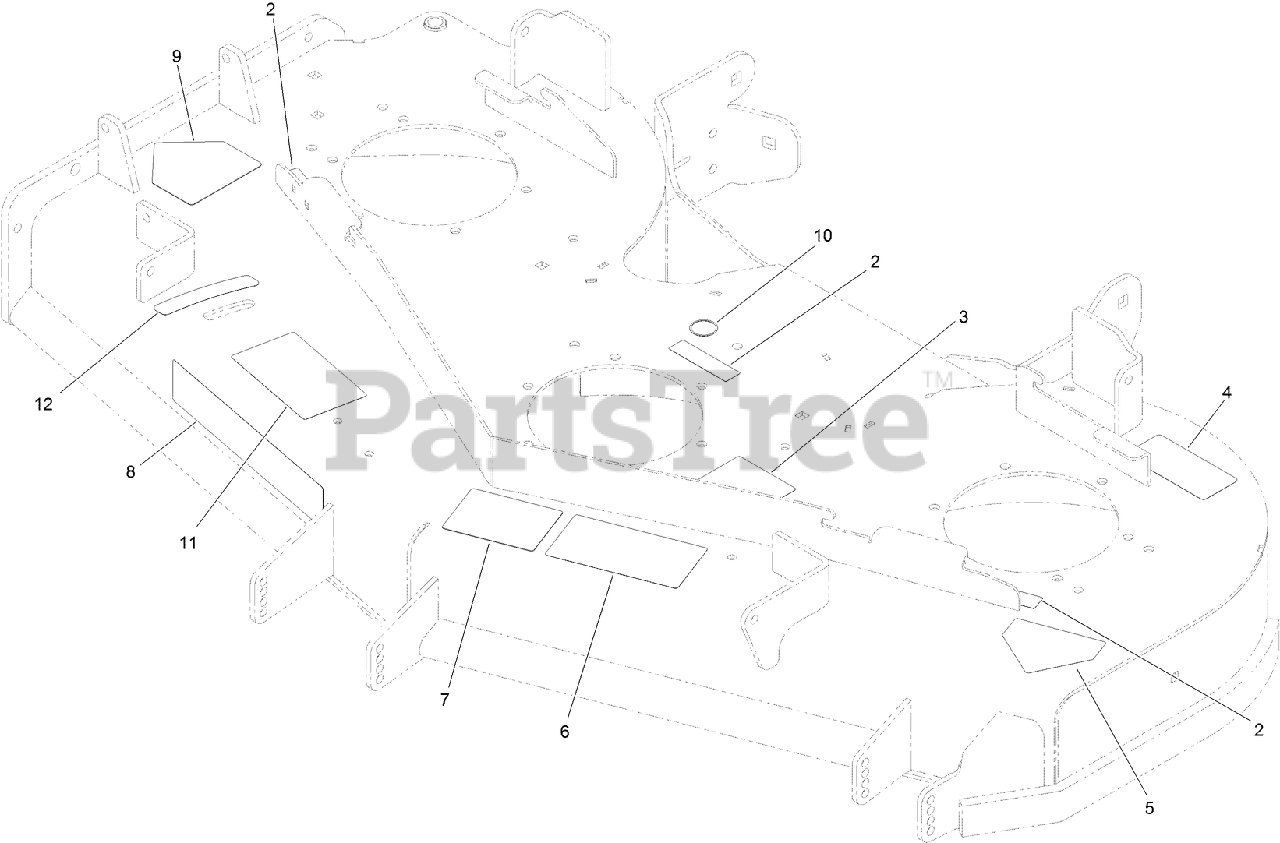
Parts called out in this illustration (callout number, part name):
2	DECAL-COVER, MISSING
3	DECAL-ROUTING, DECK BELT
4	DECAL-TORQUE
5	DECAL-DANGER
6	DECAL-DANGER, THROWN OBJECT
7	DECAL-SCALP, ANTI
9	DECAL-DANGER
10	DECAL-GREASE
11	DECAL-ADJUSTMENT, BAFFLE
12	DECAL-SETTING, BAFFLE
